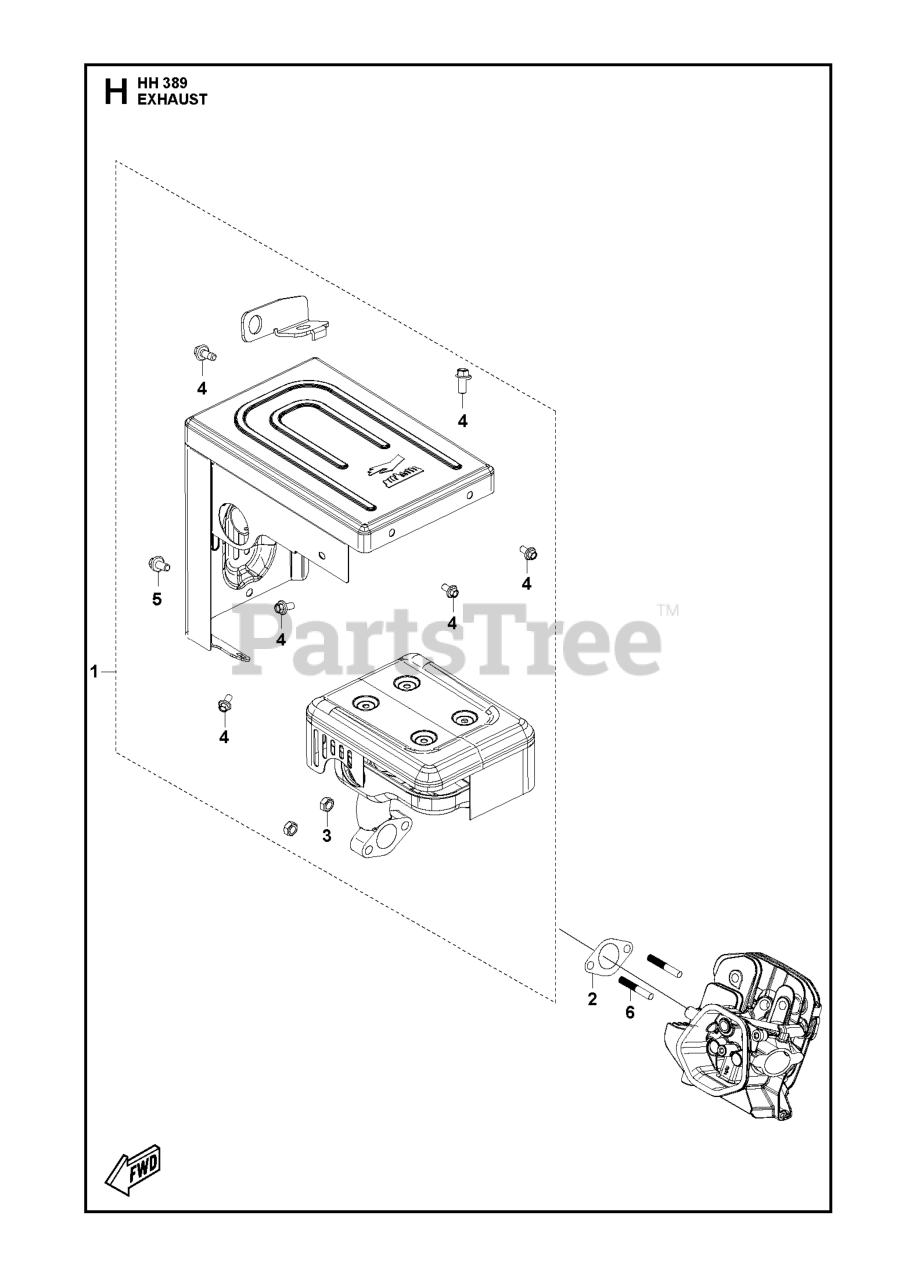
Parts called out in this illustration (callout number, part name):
1	MUFFLER ASSY
2	GASKET MUFFLER GASKET
4	BOLT
5	BOLT
